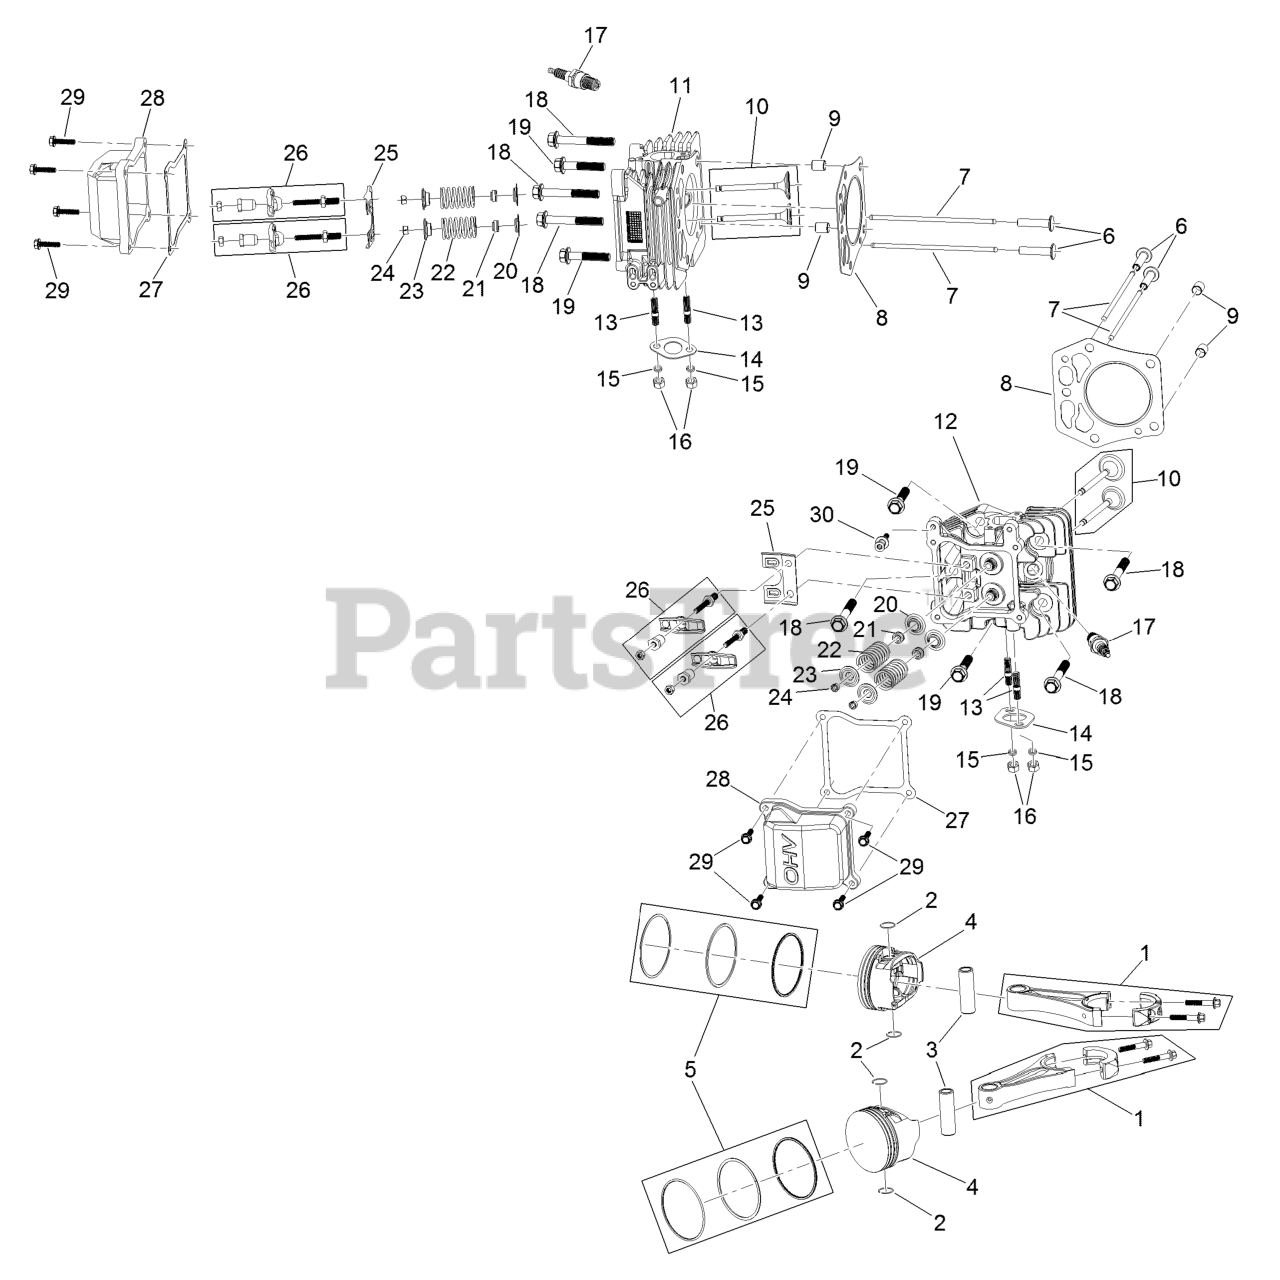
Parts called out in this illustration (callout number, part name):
1	CONNECTING ROD ASM
2	CLIP-PIN, PISTON
3	PIN-PISTON
5	PISTON RING SET
6	LIFTER-VALVE
7	ROD-PUSH
8	GASKET-HEAD, CYLINDER
9	PIN-DOWEL
10	VALVE SET
11	HEAD-CYLINDER
12	HEAD-CYLINDER
14	GASKET-EXHAUST
15	WASHER-LOCK, SPLIT
17	SPARK PLUG
18	SCREW-HWH
19	SCREW-HWH
20	SEAT-SPRING, VALVE
21	SEAL-STEM, VALVE
22	SPRING-VALVE
23	RETAINER-SPRING, VALVE
24	KEEPER-VALVE
25	PLATE-GUIDE, PUSH ROD
27	GASKET-VALVE COVER
28	COVER-VALVE
29	SCREW-HHF
30	SCREW-SHOULDER, HH
